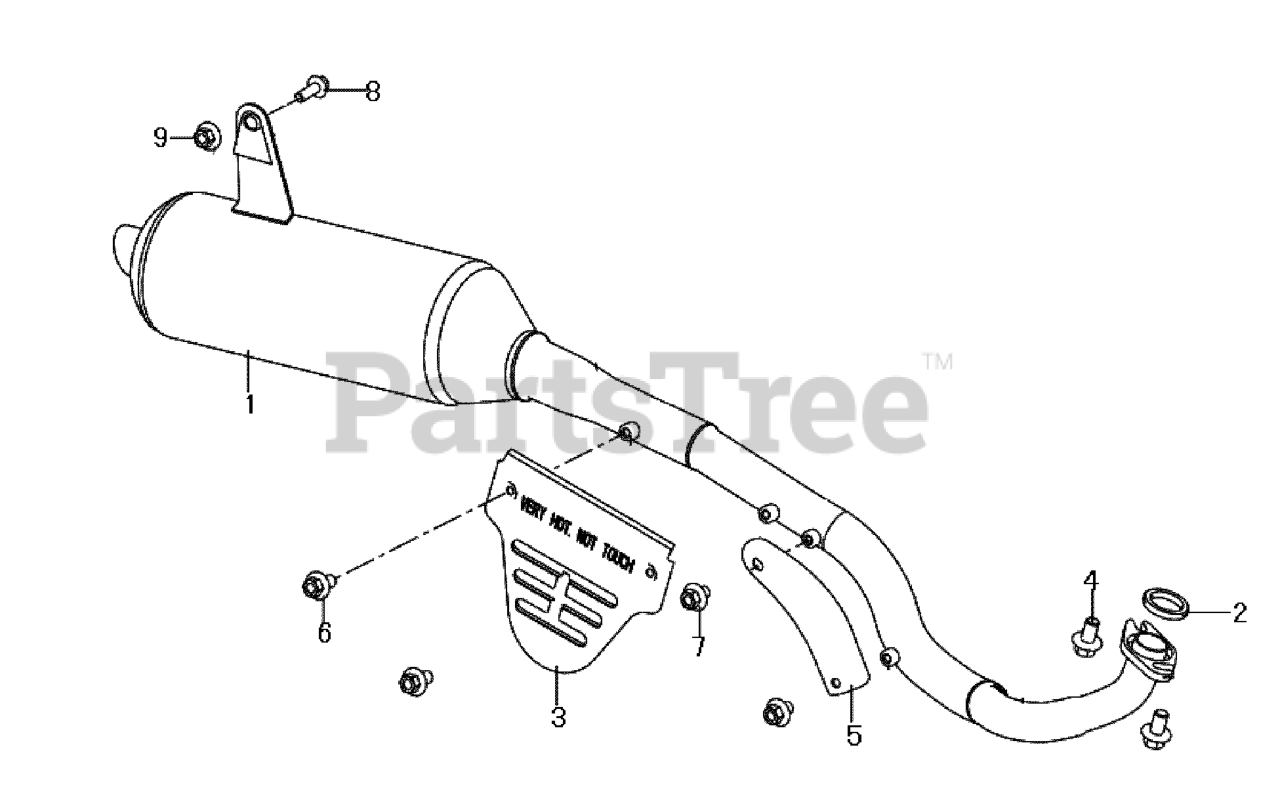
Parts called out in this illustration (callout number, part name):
1	MUFFLER ASSY.
2	GASKET, EXHAUST
3	GUARD, EXHAUST
